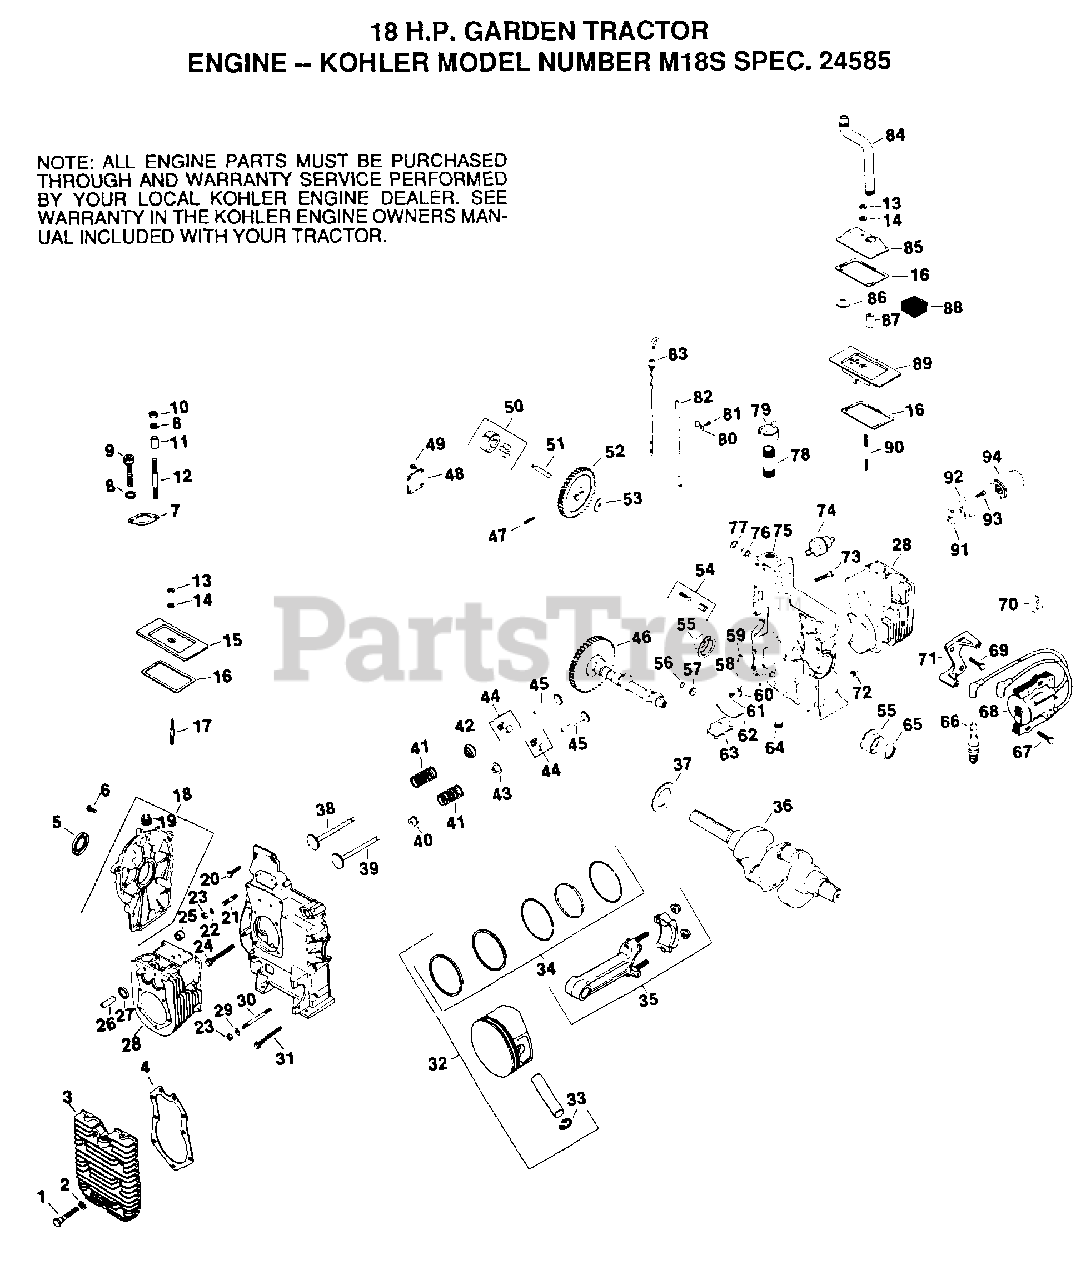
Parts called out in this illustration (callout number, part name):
2	WASHER
3	HEAD, CYLINDER
5	SEAL
6	SCREW
7	GASKET, EXHAUST
8	WASHER
9	SCREW
10	NUT
13	NUT
14	WASHER
15	COVER, #2 CYLINDER VALVE
17	STUD
19	PLUG
23	NUT
25	BUSHING, LOCATING
27	INSERT, VALVE SEAT
28	KIT, CYLINDER BARREL
30	STUD
32	PISTON W/RING SET
32A	PISTON W/RING SET .003"
32B	PISTON W/RING SET .010"
32C	PISTON W/RING SET .020"
32D	PISTON W/RING SET .030"
33	RETAINER, PISTON PIN
34	RING SET, .003"
34A	RING SET, .010"
34B	RING SET, 020"
34C	RING SET, .030"
35	CONNECTING ROD
35A	CONNECT. ROD .010"
37	WASHER, .119/.122 (A.R.)
37A	WASHER, .128/.131
37B	WASHER, .137/.140 (A.R.)
38	VALVE, EXHAUST
39	VALVE, INTAKE
43	RETAINER, INTAKE VALVE
47	PIN, ROLL
48	COVER OIL PUMP
49	SCREW
51	SHAFT OIL PUMP
52	GEAR OIL PUMP
58	TUBE, DIPSTICK
59	PLUG, CUP
61	SCREW
62	CLAMP, SPRING
63	HOUSING, OIL PICKUP
64	PLUG
67	SCREW, 1/4-20 X 1
72	PLUG
74	OIL PRESSURE SWITCH
77	RING, RETAINING
81	SCREW
82	TUBE, OIL LEVEL
83	DIPSTICK, BLADE 11-5/16
84	HOSE, BREATHER
86	VALVE, BREATHER
87	SEAL BREATHER
88	FILTER, BREATHER
89	COVER, #1 LOWER CYLINDER VALVE
90	STUD
92	ADAPTER, OIL FILTER
93	SCREW
